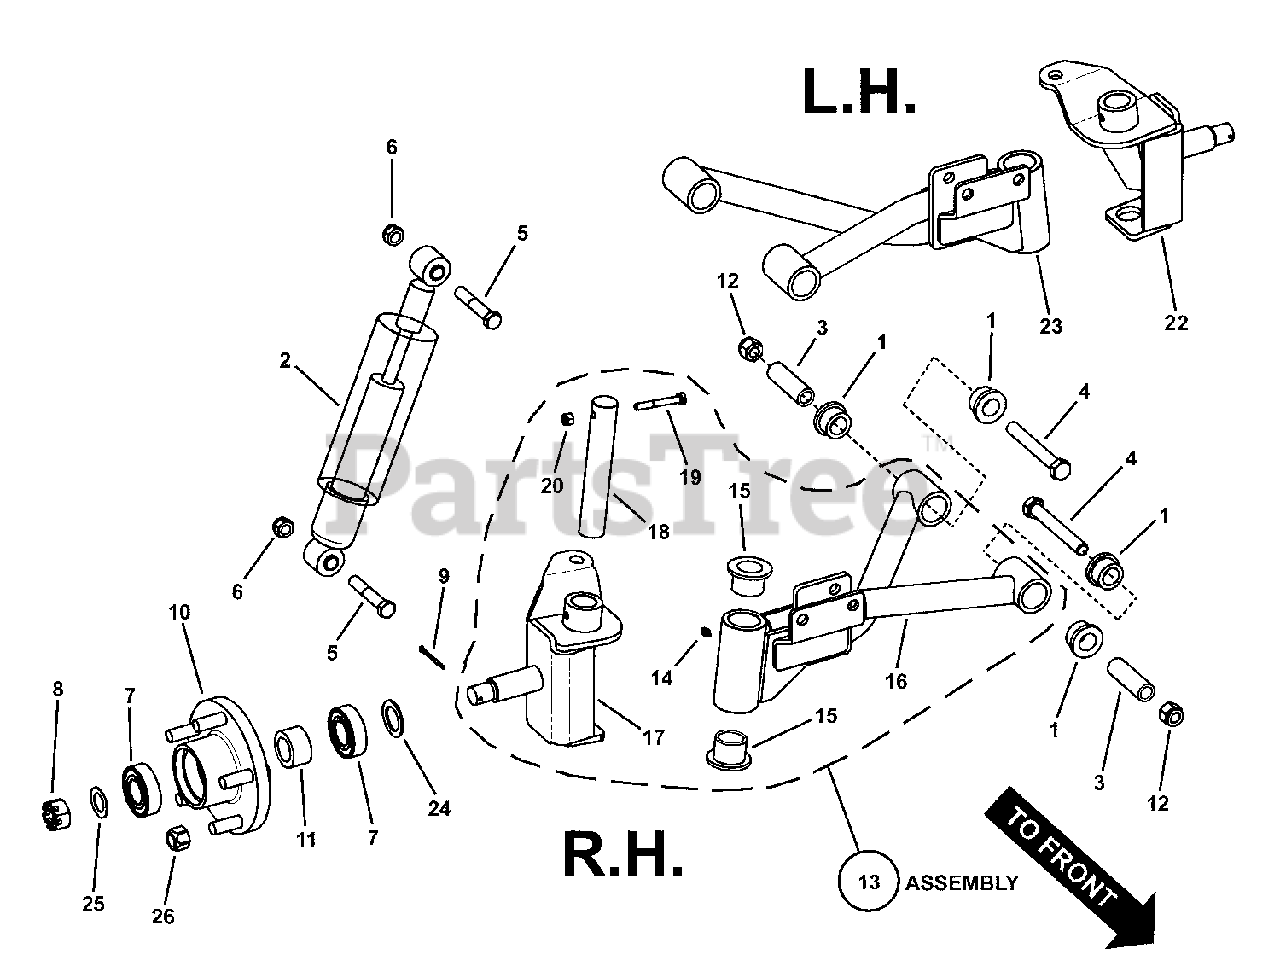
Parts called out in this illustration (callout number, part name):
1	BUSHING, Suspension
2	ASSEMBLY, Shock/Spring
3	SLEEVE, Suspension
4	BOLT, 1/2-13 x 3-3/4" Hex Head, GR 5
5	SCREW, 7/16-20 x 2-1/2" Hex Head Cap (Special) GR 5
6	NUT, 7/16-20 Hex Top Lock
7	BEARING, BALL, .98" ID, 2.04" OD, .59" Wide
8	NUT, 3/4-16 Slotted Hex, GR 5
9	PIN, Cotter 1/8 x 1-1/4"
10	WHEEL HUB, Front
11	SPACER, Front Wheel
12	NUT, 1/2-13 Hex Nyloc
13	R/B 7053445, ASSY, RH A-Arm & Spindle
14	LUBE FITTING, 3/16" Serrated
15	BUSHING, Caster
16	A-ARM ASSEMBLY, RH
17	SPINDLE WELDMENT, RH
18	ROD, Spindle Pivot
19	SCREW, 1/4-20 x 2" Hex Head Cap, GR 5
20	NUT, 1/4-20 Hex Nyloc
22	SPINDLE, WELDMENT, LH
23	A-ARM ASSEMBLY, LH
24	BUSHING, 14 Gage Machine
25	THRUST WASHER, 3/4" I.D.
26	LUG NUT, 1/2-20 Hex
